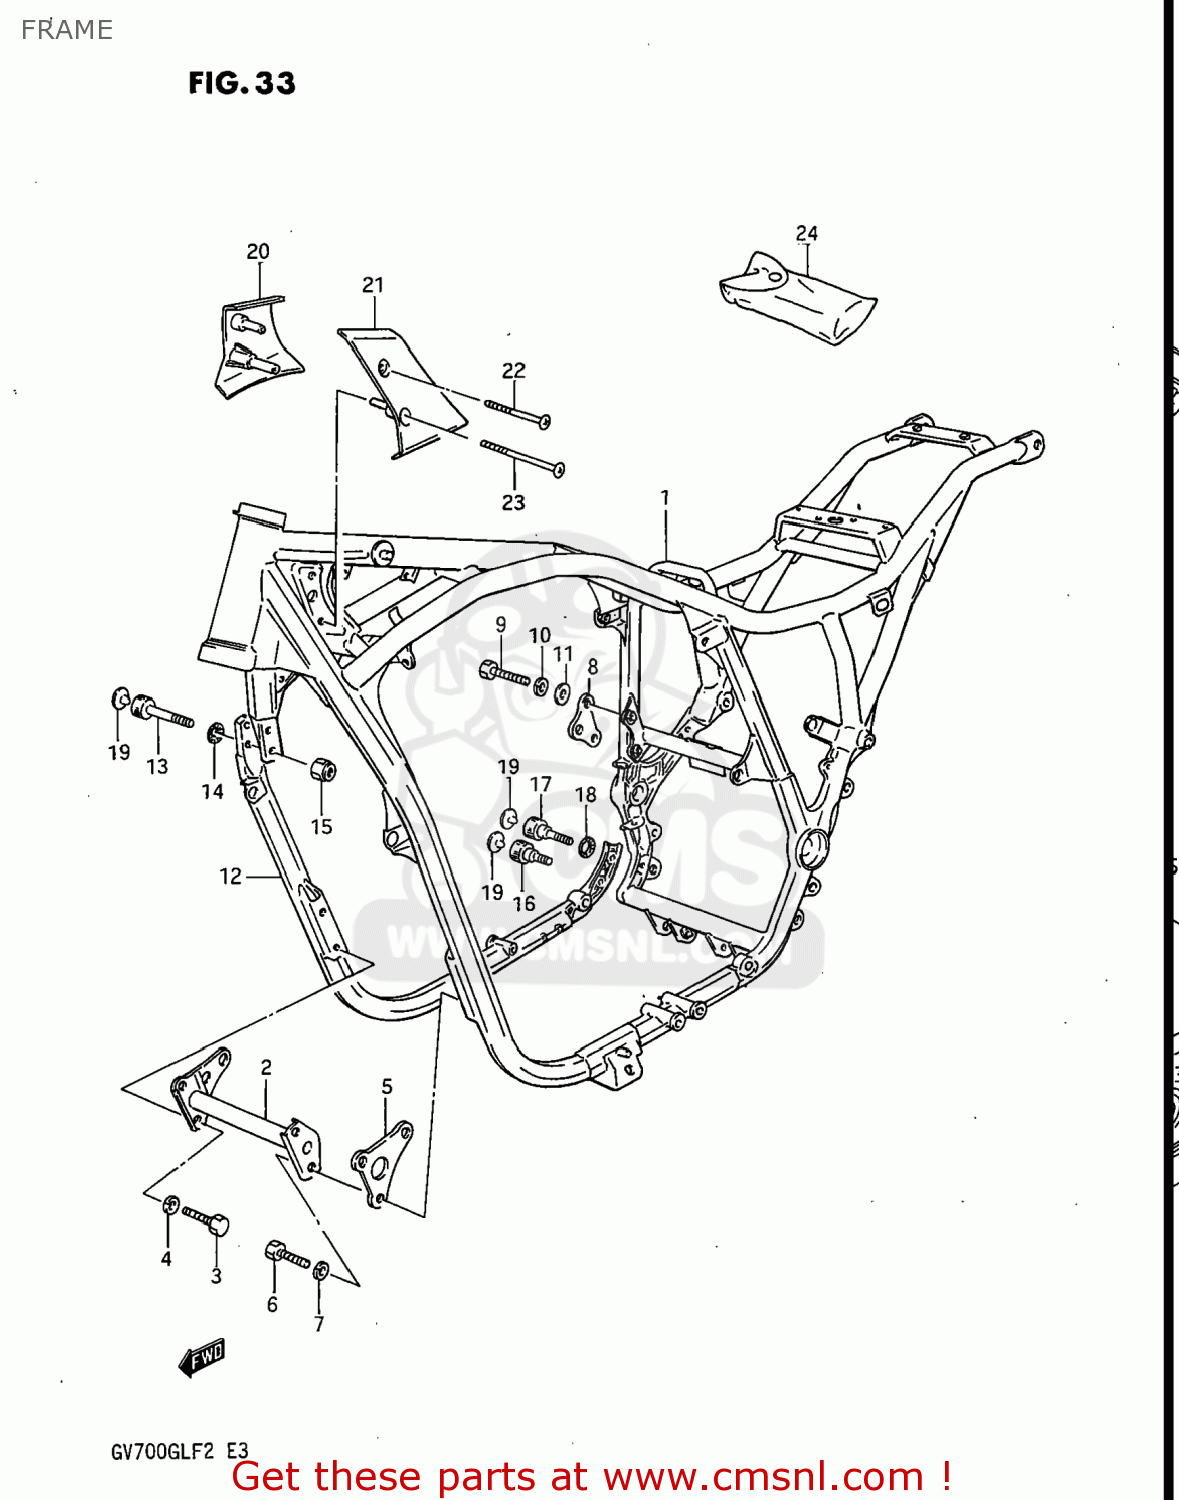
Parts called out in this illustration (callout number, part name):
1	FRAME
2	PLATE COMP,ENGINE MOUNTING
3	BOLT
4	WASHER,LOCK,8.
5	PLATE,ENGINE MOUNTING
6	BOLT
7	WASHER,LOCK,8.
8	PLATE,ENGINE MOUNTING
9	BOLT
10	WASHER,LOCK,8.
11	WASHER
12	TUBE,FRAME
13	BOLT 10X38
14	WASHER
15	NUT 10MM
16	BOLT
17	BOLT
18	WASHER
19	CAP
20	COVER,FRAME HEAD,RIGHT
21	COVER,FRAME HEAD,LEFT
22	SCREW, LOWER
23	SCREW
24	TOOL ASSY
